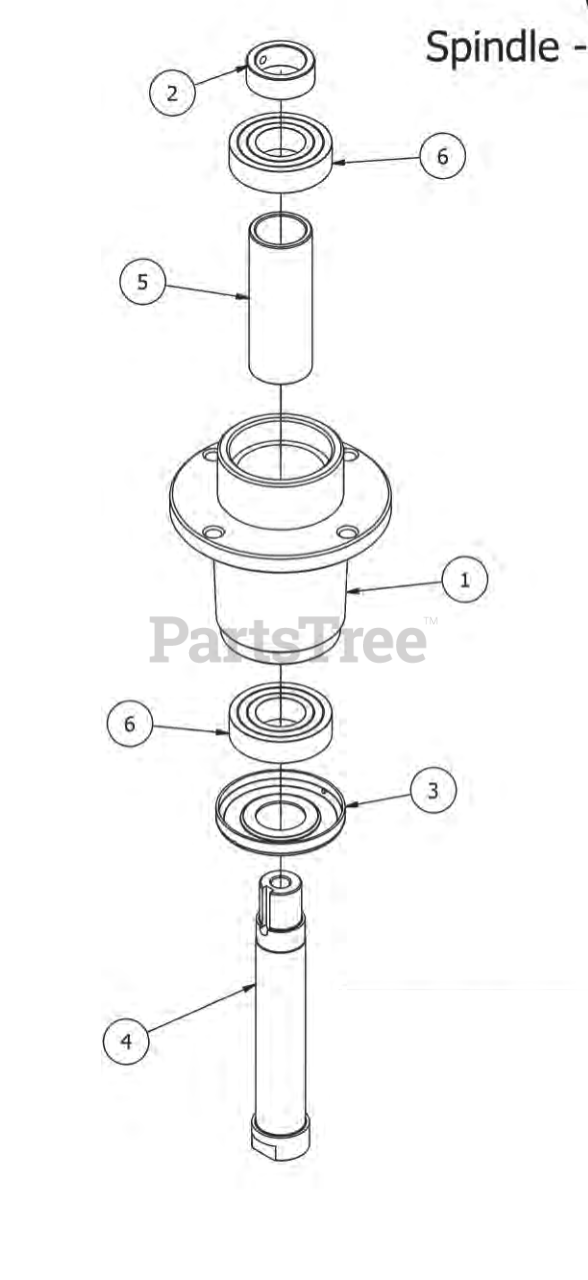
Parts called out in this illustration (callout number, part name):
1	ZT spindle housing
2	Locking Collar w/ 1/4"-20 Set Screw
3	Spindle Dust Cap
4	ZT-AOS Spindle Shaft
5	ZT spindle spacer
6	Bearing - 6206
